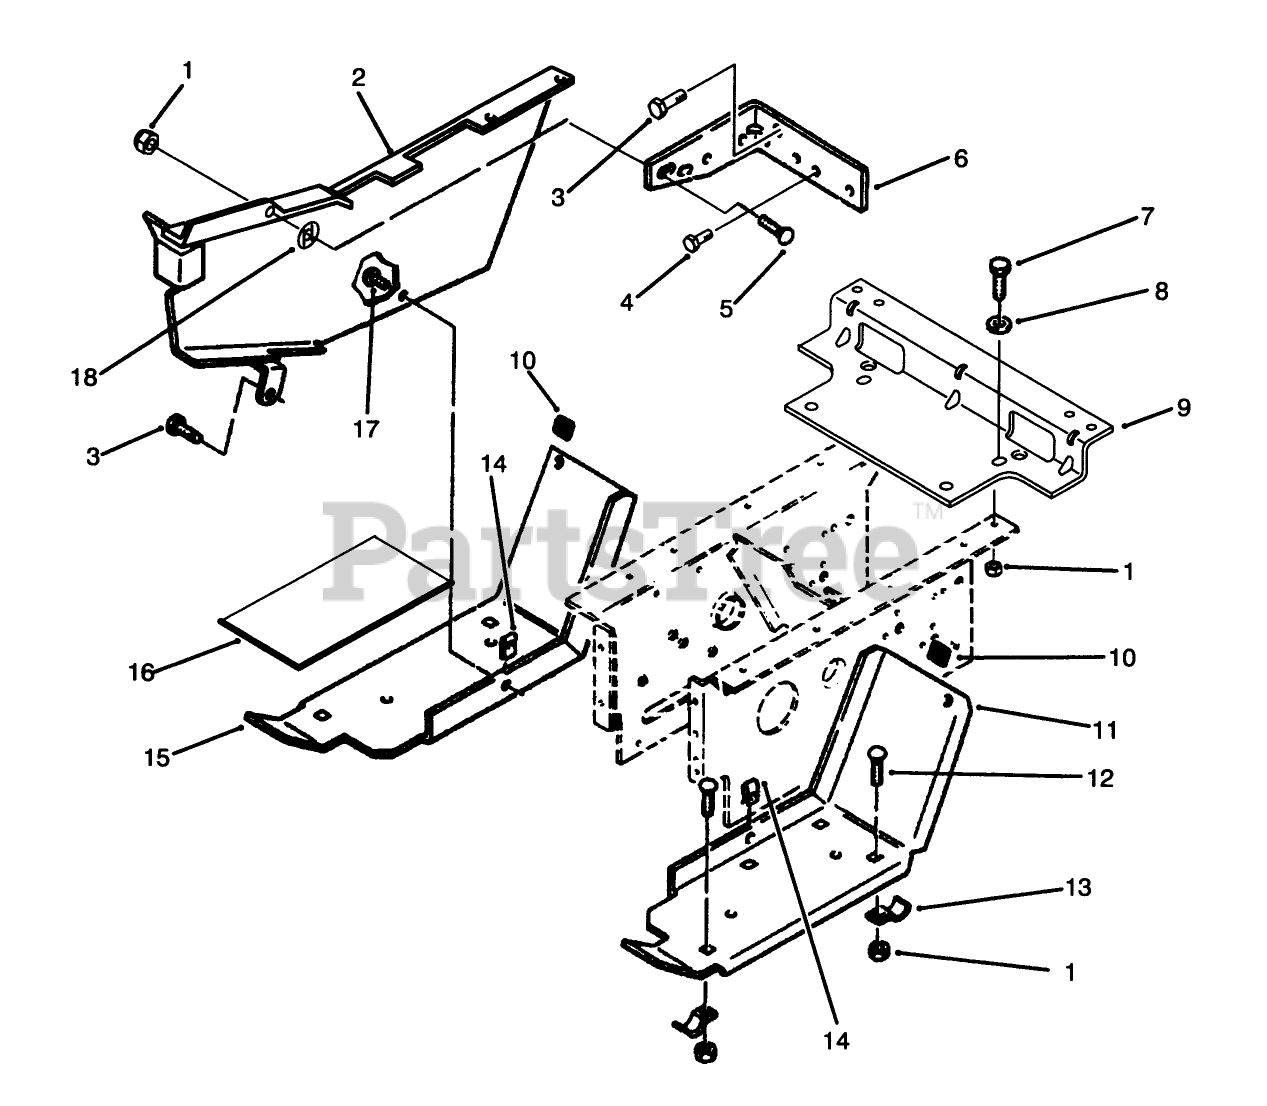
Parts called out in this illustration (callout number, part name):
1	NUT-LOCK, NI
2	GUARD - BELT WA *R
3	SCREW
4	Bolt
5	BOLT-CARR
6	BRACKET-BELT*B
7	SCREW-HH
8	WASHER-PLAIN
10	BUMPER
11	FOOTREST LH *R
12	BOLT-CARR
13	BRACKET
16	PAD FOOTREST
